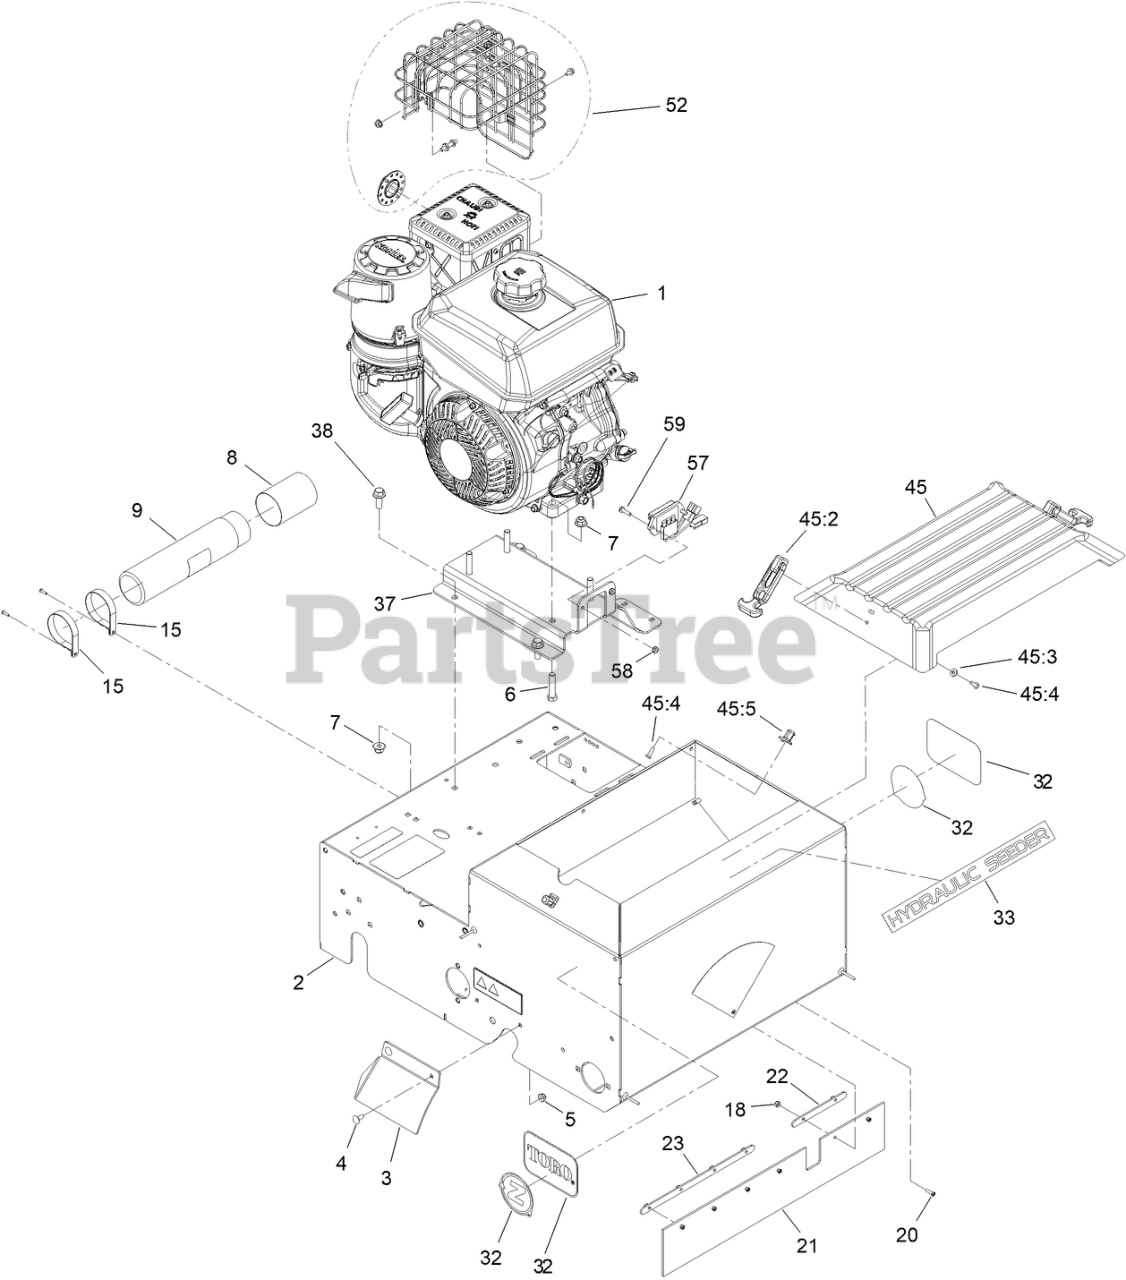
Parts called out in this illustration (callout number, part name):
2	FRAME-SERVICE ASM
3	GUARD-RH
4	SCREW-CARR
5	NUT-HF
6	SCREW-HH
7	NUT-HF, NI
8	CAP-HOUSING
9	TUBE-MANUAL
15	CLAMP-R
18	NUT-LOCK
20	SCREW-SHH
21	GUARD-DUST
22	PLATE-RETAINER
23	PLATE-RETAINER
32	DECAL
37	PLATE-ENGINE
38	SCREW-HHF
45	SEEDER COVER KIT
45:2	LATCH-RUBBER
45:3	WASHER-FLAT
45:4	SCREW-PPH
45:5	LATCH-KEEPER
52	KIT-CH395 MUFFLER GUARD
57	REGULATOR
58	NUT-KEPS
59	SCREW-HWH
